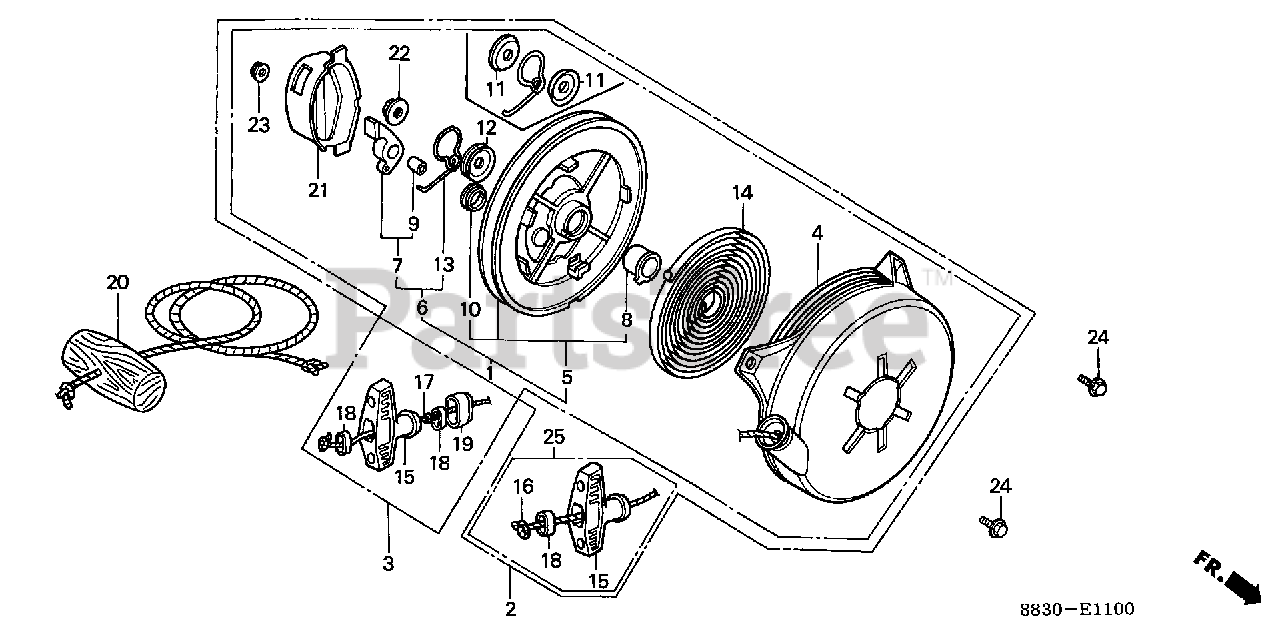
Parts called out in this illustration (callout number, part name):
1	REEL KIT, STARTER Use up to Engine SN 1533900.
2	STARTER ASSY., RECOIL *R8* Use up to Engine SN 1132419.
2	STARTER ASSY., RECOIL *R8* (BRIGHT RED)
4	CASE, STARTER *R8* Use up to Engine SN 1045974.
4	CASE, STARTER *R8* (BRIGHT RED)
5	REEL KIT, STARTER Use up to Engine SN 1132419.
5	REEL KIT, STARTER
5	REEL, STARTER
6	RATCHET KIT
7	RATCHET KIT Use up to Engine SN 1132419.
7	RATCHET
8	BOSS, REEL
8	BOSS, REEL Use up to Engine SN 1533900.
9	BUSH, RATCHET Use up to Engine SN 1533900.
9	BUSH, RATCHET
10	BUSH, REEL STARTER
11	PLATE, FRICTION Use up to Engine SN 1533900.
12	PLATE, FRICTION
13	RATCHET KIT Use up to Engine SN 1132419.
13	SPRING, FRICTION
14	SPRING, RETURN
15	GRIP, STARTER
16	ROPE, STARTER
18	SUPPORT, GRIP
20	ROPE, STARTER Use from Engine SN 1779881.
21	COVER, STARTER REEL Use up to Engine SN 1533900.
21	COVER, STARTER REEL
22	NUT, SELF-LOCK (8MM)
23	NUT, FLANGE (5MM)
24	BOLT, FLANGE (6X8)
